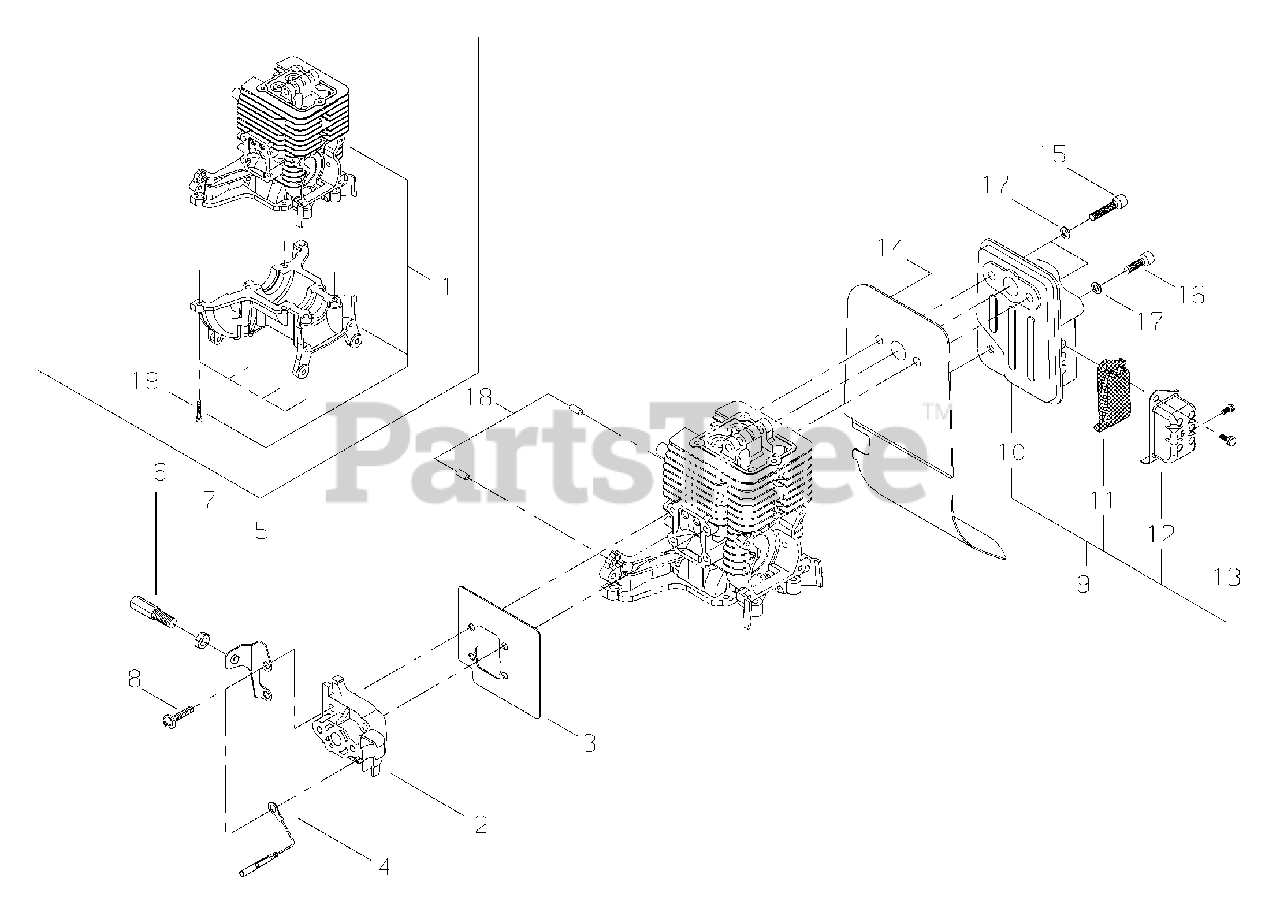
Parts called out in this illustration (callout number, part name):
1	CYLINDER BLOCK SET
2	VALVE, REED
3	DEFLECTOR, HEAT
4	LEAD - GROUND
5	BRACKET, THROTTLE CABLE
6	NUT, CABLE ADJUST
7	LOCKNUT - 6
8	SCREW - 5X25
9	MUFFLER ASSY
10	MUFFLER
11	SCREEN, SPARK ARRESTOR
12	GUIDE, EXHAUST
13	SCREW - 4X6
14	SHIELD, EXHAUST
15	SCREW - 5X25
16	SCREW - 5X16
17	WASHER - 5
18	PIN - LOCATING
19	SCREW - 5X16
